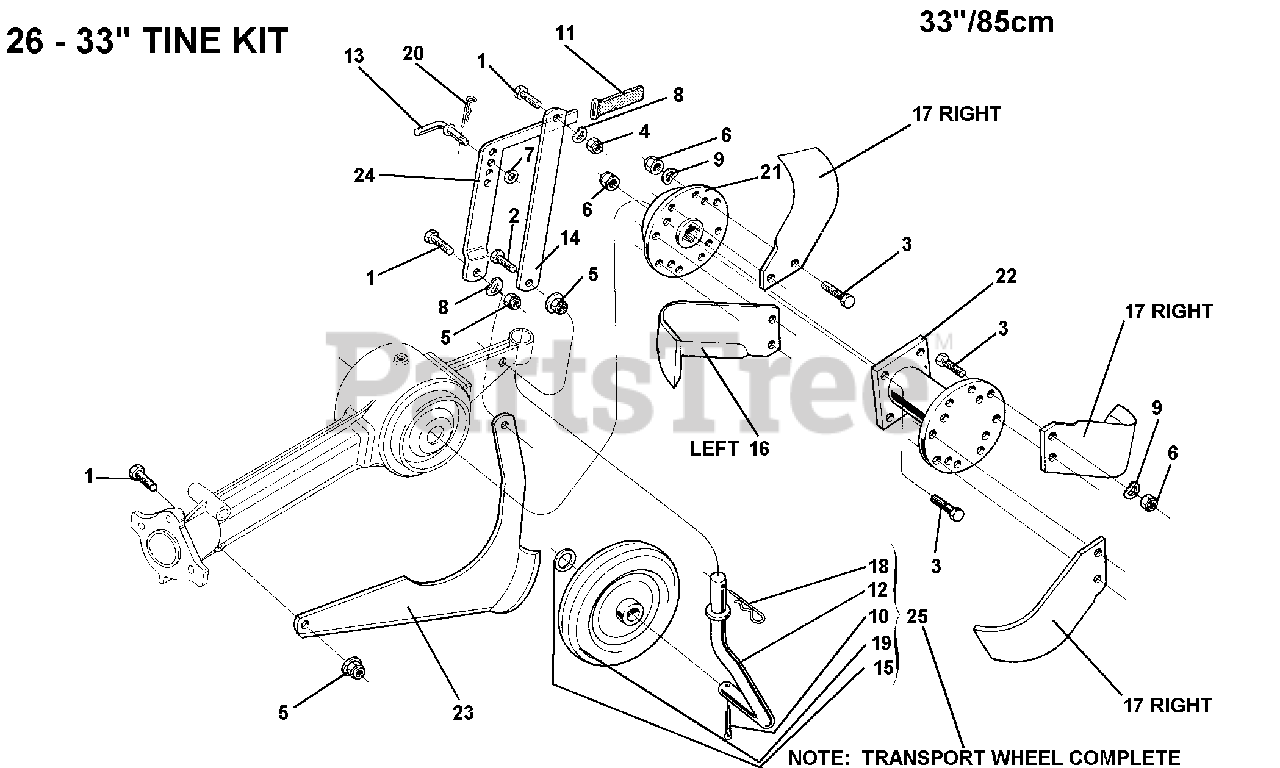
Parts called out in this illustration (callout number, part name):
1	SCREW M10 X 30
2	SCREW TE M10 X 35 UNI 5739-8G
3	SCREW TE M12 X 35 UNI 5739-8G
4	NUT, SELF LOCKING M10
6	NUT, SELF LOCKING M12
7	WASHER P10.5 X 18
8	WASHER, LOCK 10.5
9	WASHER, LOCK 13
10	PIN, COTTER A 4 X 30 UNI 1336
12	WHEEL SUPPORT PIN
13	ADJUSTMENT PIN
15	SPACER RING
17	RIGHT KNIFE, WIDE
19	RUBBER WHEEL D 22
21	BLADE HOLDER FLANGE
22	KNIFE SPACER
23	CENTRAL KNIFE
25	TRANSPORT WHEEL ASSEMBLY
26	33" TINE KIT
